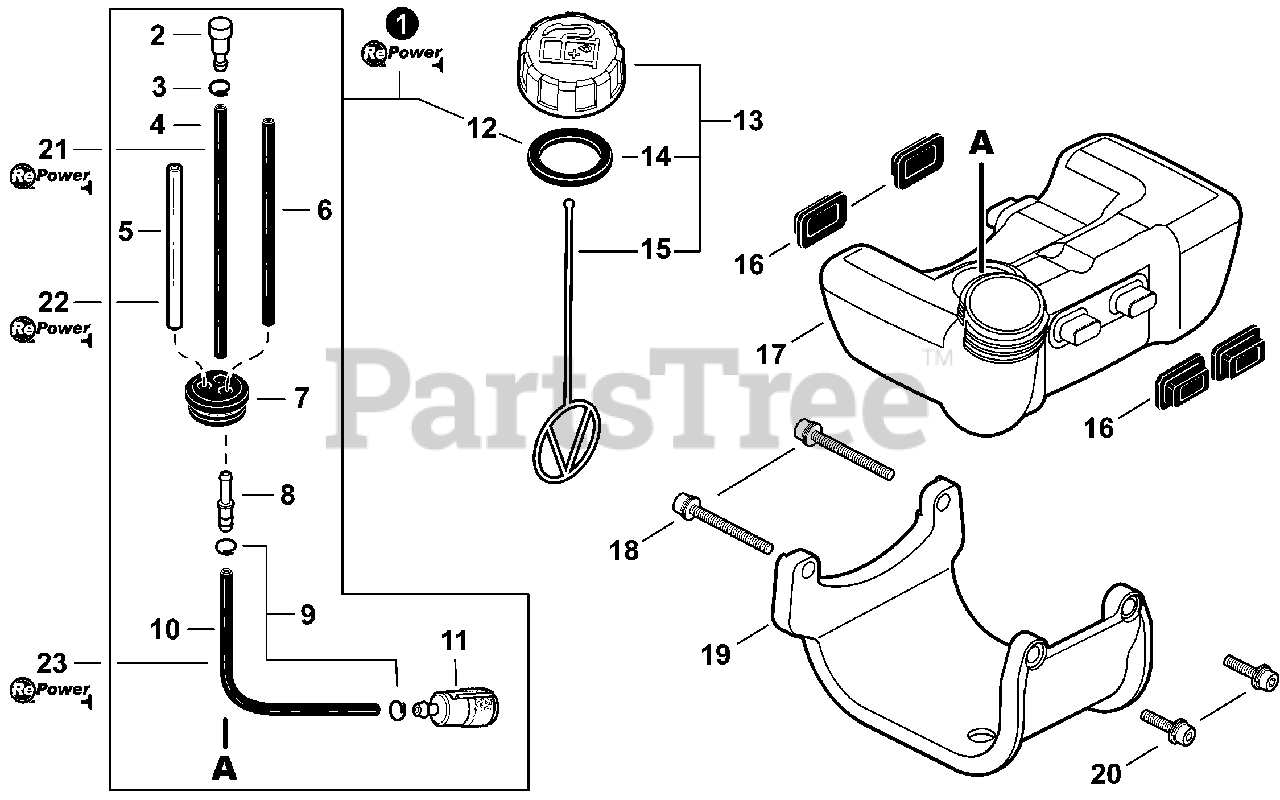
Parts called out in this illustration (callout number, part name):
1	FUEL SYSTEM KIT - REPOWER
2	VENT ASSY
3	CLIP Ø6.5MM
4	PIPE, FUEL 3×6×105 BLACK
5	PIPE, FUEL 3×6×85 CLEAR
6	PIPE, FUEL 3×5×74 BLACK
7	GROMMET, FUEL
8	CONNECTOR, PIPE Ø5ר3.5
9	CLIP Ø6
10	PIPE 3×5×140 BLACK
11	FILTER, FUEL 125-528
12	GASKET, FUEL CAP
13	CAP ASSY, FUEL
14	GASKET, FUEL CAP
15	CONNECTOR, CAP L=123
16	CUSHION, FUEL TANK
17	TANK, FUEL
18	BOLT 5×40
19	GUARD, FUEL TANK
20	BOLT 5×18
21	PIPE - REPOWER BULK 3×6mm BLACK
22	PIPE - REPOWER BULK 3×6mm CLEAR
23	PIPE - REPOWER BULK 3×5mm BLACK
